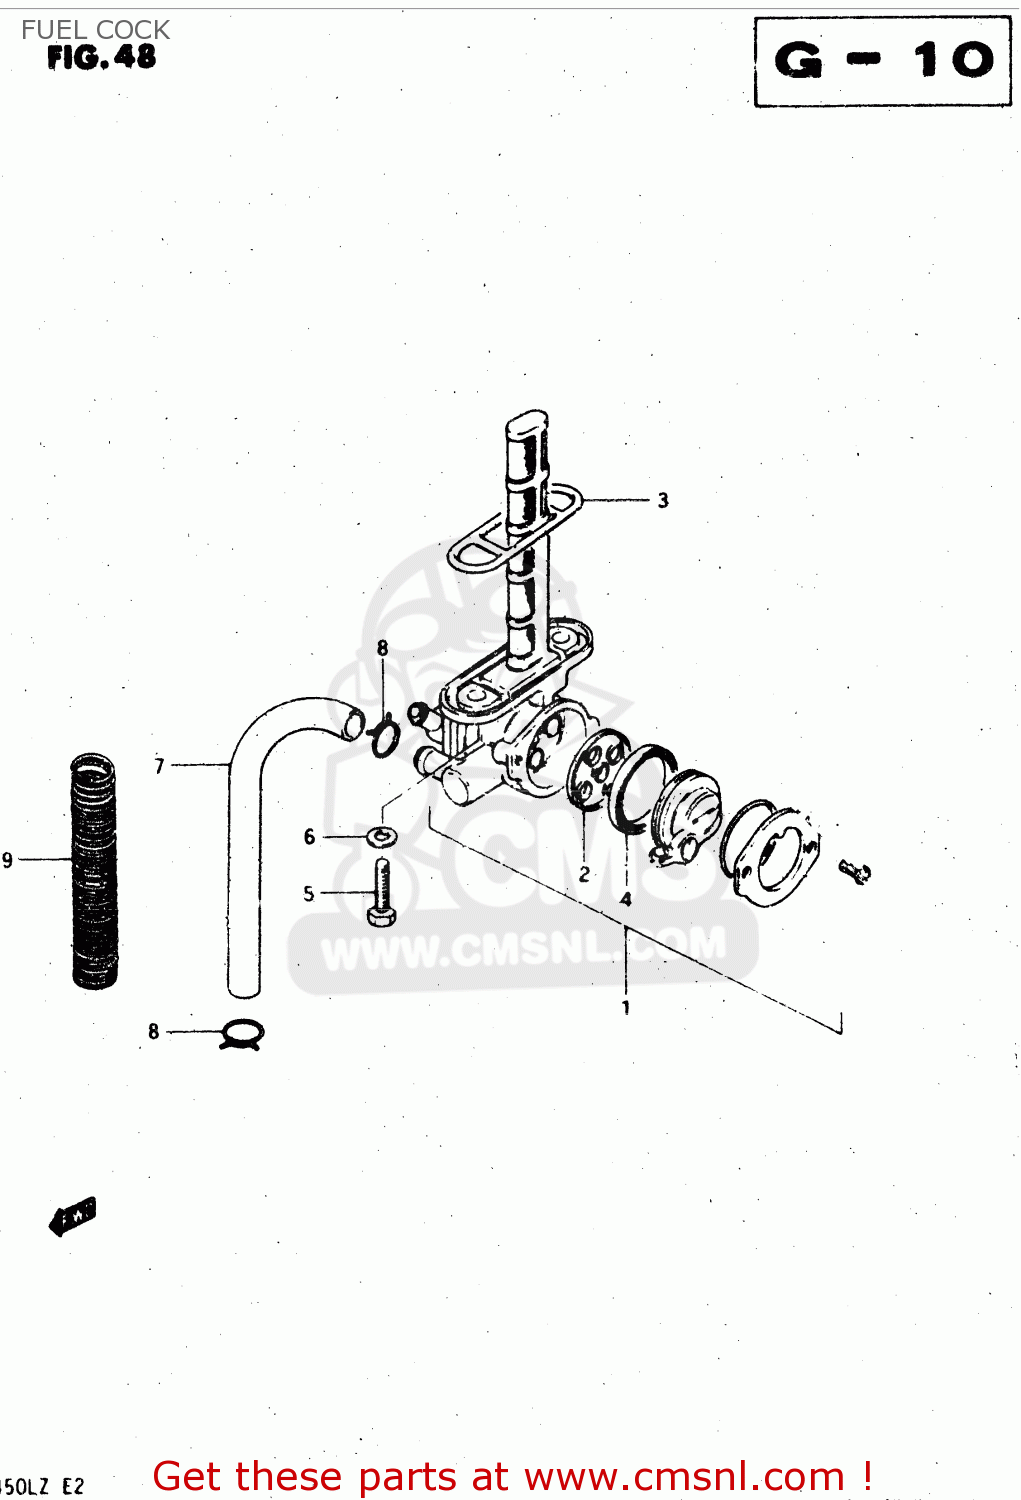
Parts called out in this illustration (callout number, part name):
1	COCK ASSY,FUEL
2	GASKET (NAS)
3	GASKET, FUEL COCK (NAS)
4	V SEAL,FUEL COCK
5	SCREW
6	GASKET
7	HOSE
8	CLIP
9	SPRING
